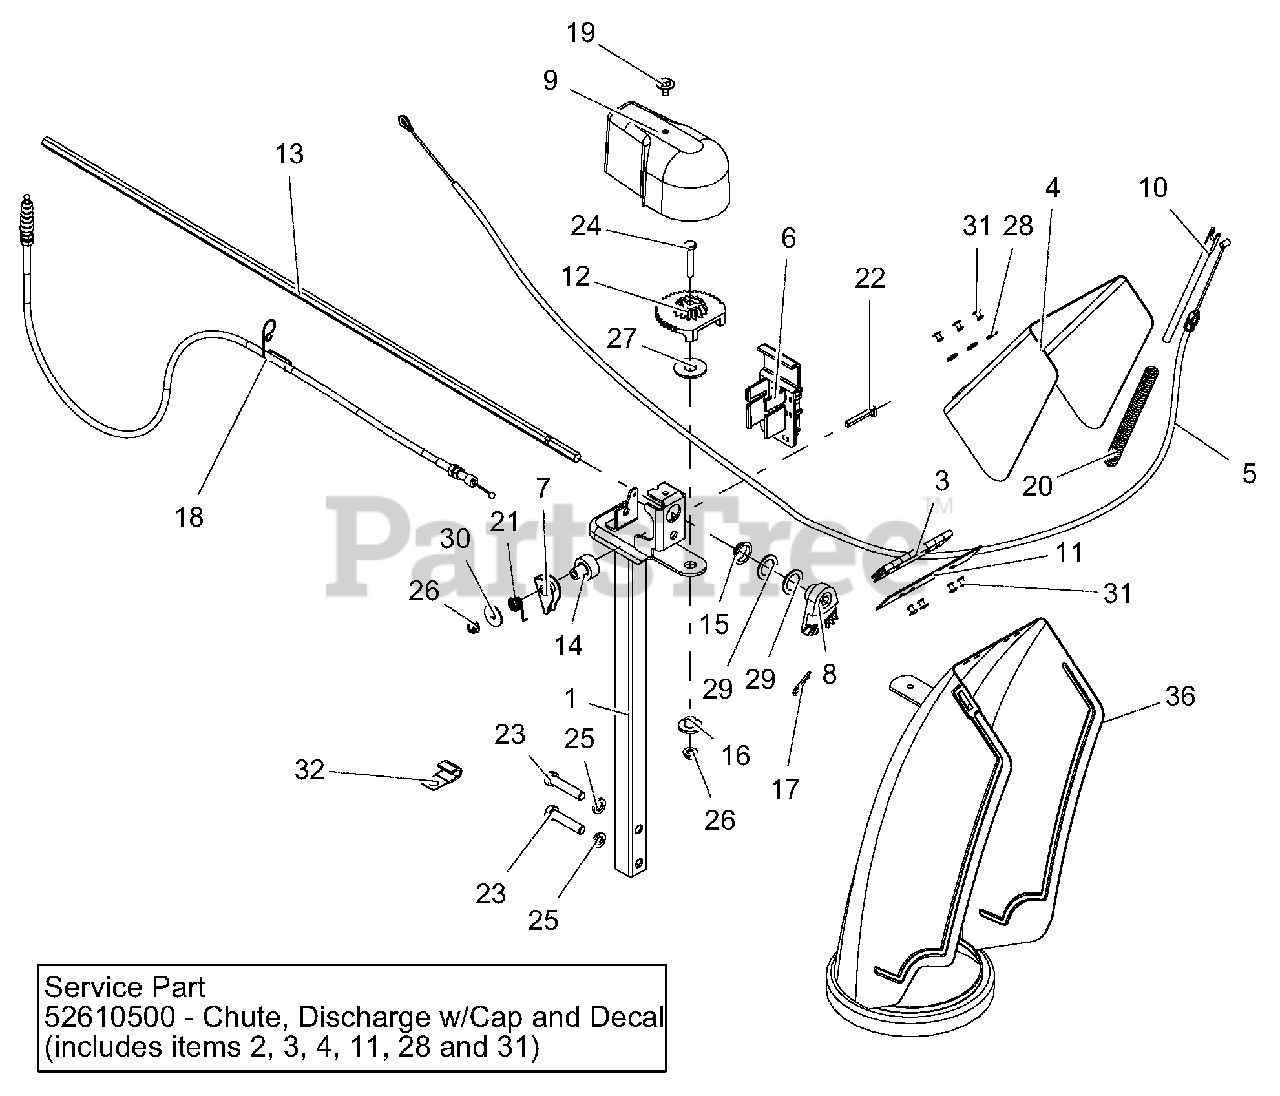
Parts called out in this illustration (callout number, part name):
1	PEDESTAL, CHUTE - QUICK STICK
4	CAP, LARGE
5	CABLE, DEFLECTOR-COATED
6	HOLDER W LARGE SHEAR BOLT /NUT
7	ARM, LOCKING
8	GEAR, CHUTE-ACTUATION
9	COVER, CHUTE GEAR
10	ROD, DEFLECTOR CAP
11	CAP SEAL 5.50
12	GEAR, CHUTE
13	ROD, HEX - CHUTE ROTATION
14	BUSHING, LOCK ARM
15	BUSHING, POLYLINER-.75 SNAPIN
16	BSHG-FLG .265X.477X.375X1.00
17	PIN-HAIR INT .08X.18X1.18 YWZC
18	CABLE, CHUTE LOCK
19	SCR-TAP .25-20X.50 LGHWH TR YZ
20	SG-COMP .08X.40X6.50 14#/IN
21	SG-TORS
22	@BLT-RDHDSQNK .25-20X1.50 G5YZ
23	@BLT-HEX .38-16X1.75 GR5 YWZC
24	@BLT-HEX .25-20X1.50 GR5 YWZC
25	@WSHR-LK .38X.094 REG YWZC
26	@NUT-LK-CTR-FLG .25-20 YWZC
27	WSHR-FLT-NYL .515X1.375X.093
28	WSHR-FL-STL .196X.500X.06 YZ
29	WSHR-FL-STL.754X1.125X.062YWZC
30	WSHR-FL-STL .281X1.000X.063
31	RVT-POP .187 YZ
32	J-CLAMP
36	CHUTE, NOTCHED DISCHARGE
